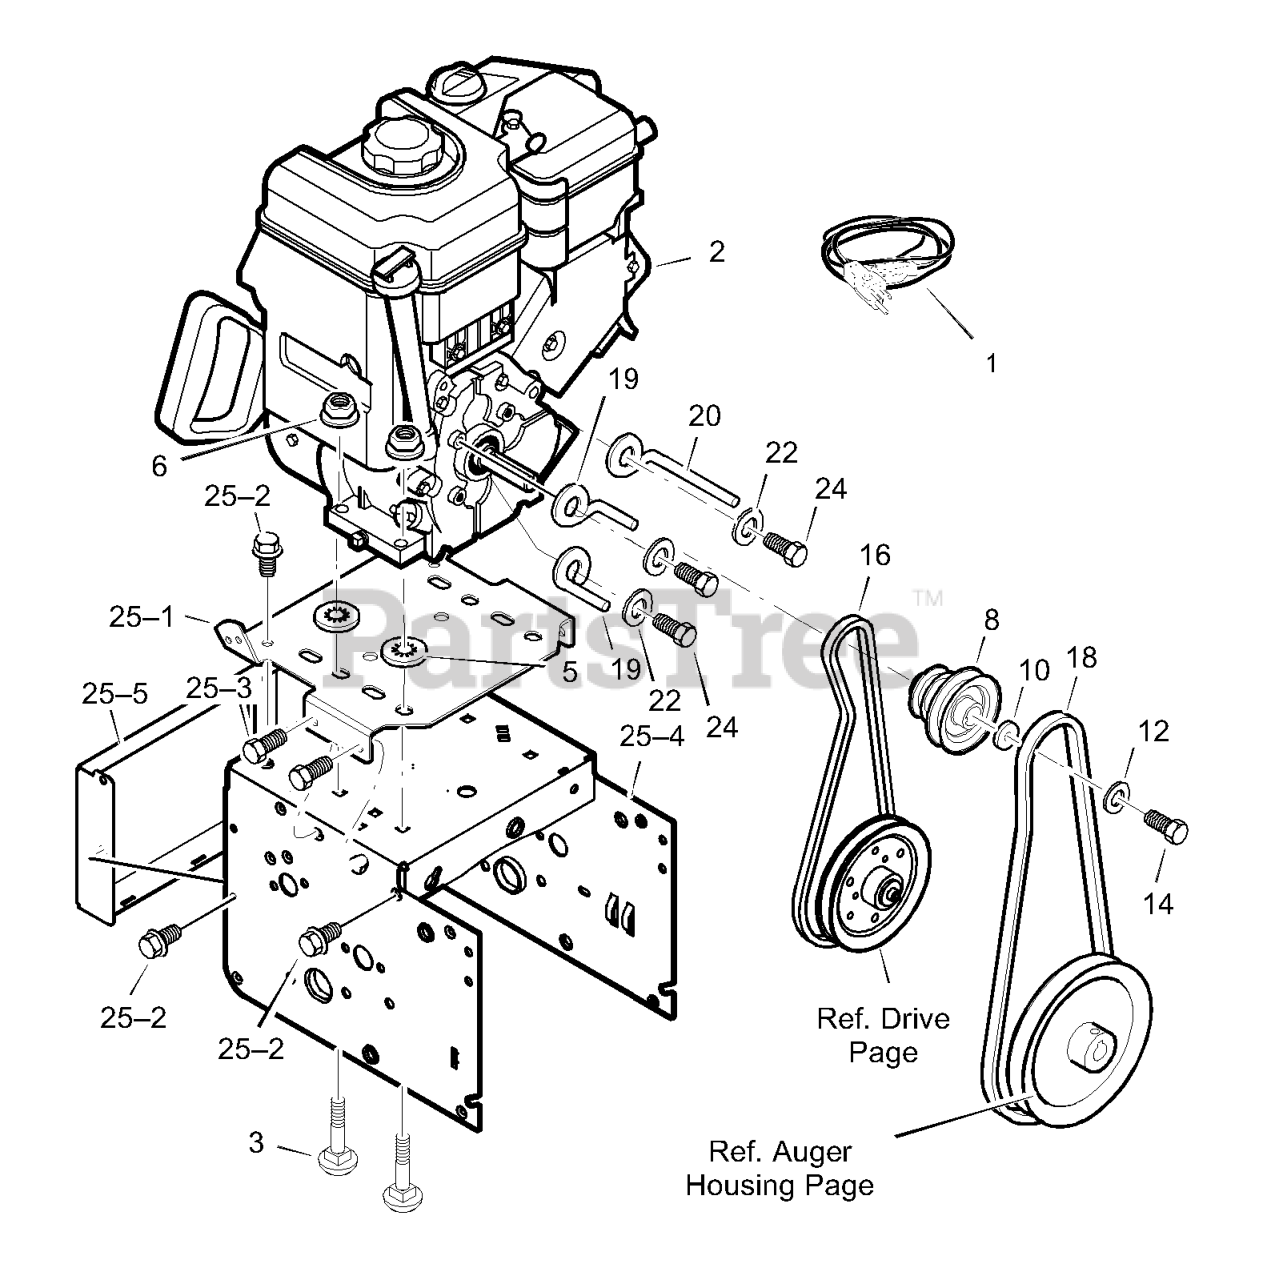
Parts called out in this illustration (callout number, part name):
1	CORD, STARTER
2	ENGINE
3	BOLT, CARRIAGE
5	RETAINER, PUSH
6	NUT, HEX 5/16-18
8	PULLEY, ENGINE
10	WASHER
12	WASHER .38ID
14	SCREW
16	BELT, HYDRO DR
18	BELT, V 4L 38.1
19	GUIDE, BELT -HYDRO
20	GUIDE, BELT
22	WASHER
25	FRAME ASSEMBLY
25-1	PLATE, ENGINE
25-2	SCREW, TAP
25-3	SCREW, TAP
25-4	FRAME, MOTORBOX
25-5	PANEL, BACK - HY
